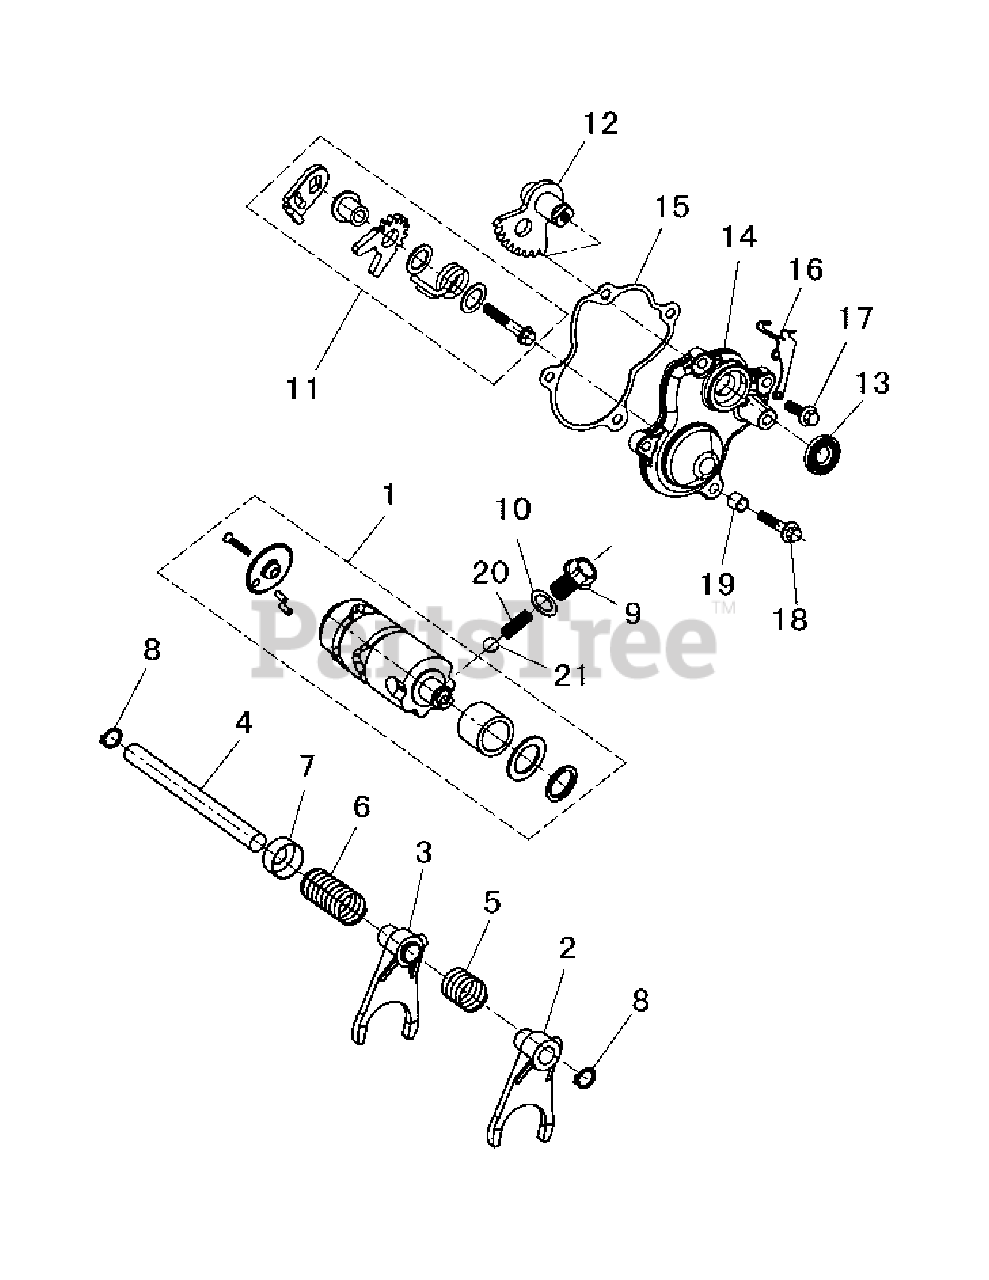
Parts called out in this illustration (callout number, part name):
1	Drum Asm-Shift
3	Fork-H, L Gear
4	Shaft-Gear Shifter
5	Spring-R Gear
6	Spring-H,L Gear
9	Bolt-M14 X 1.5 X 2
10	Washer 14×21×1
11	Shape Drive Gear-Fan
12	Shape Drive Gear-Fan
13	Oil Seal 15×25×5
14	Side Cover-Gear Rocker
15	Washer-Gear Rocker
16	Bracket-Oil Pipe
17	Flangebolt M6X20
18	Flangebolt M6X30
19	Dowel Pin 8×12
20	Spring-24 X 1
21	Steel Ball-Sr9.5
